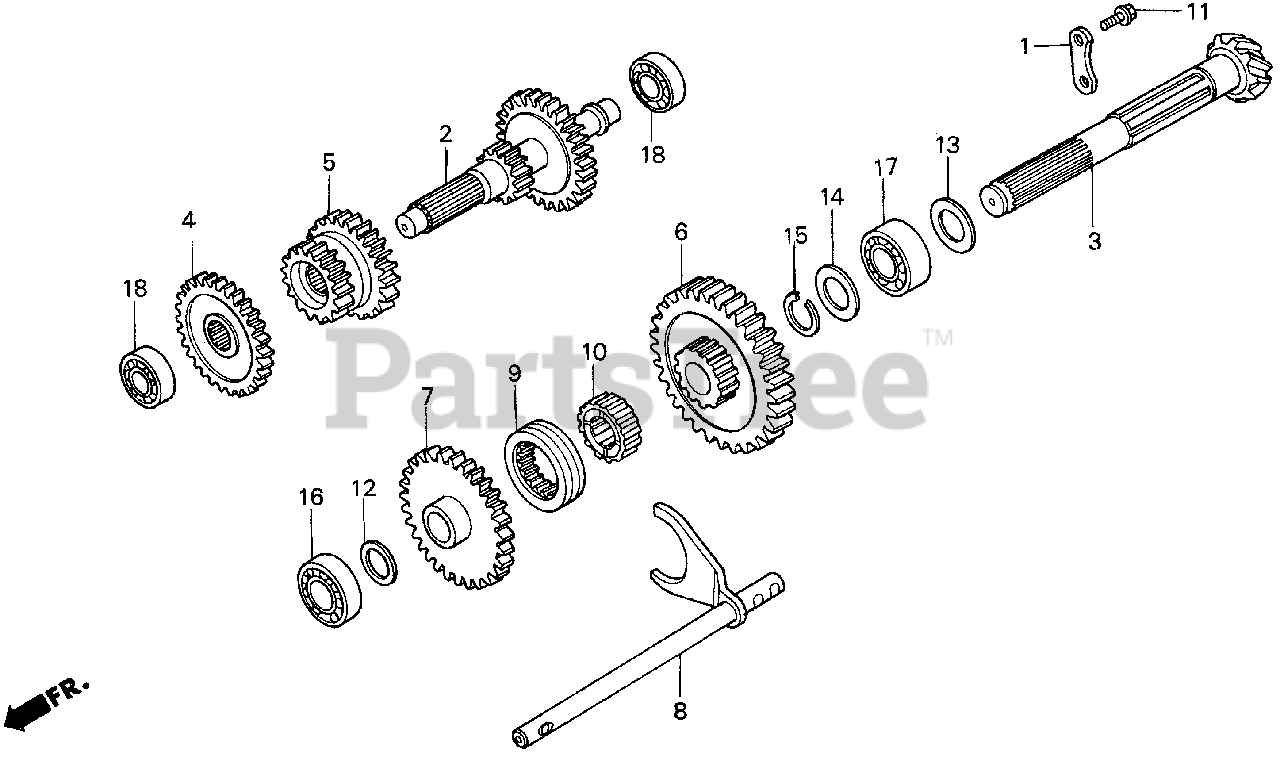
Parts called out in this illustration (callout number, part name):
1	PLATE B, BEARING STOPPER
2	COUNTERSHAFT (LOWER)
3	SHAFT, FINAL
4	GEAR, COUNTERSHAFT THIRD (39T)
5	GEAR, COUNTERSHAFT FOURTH (29T/17T)
6	SELECTOR KIT, AUXILIARY
6	GEAR, AUXILIARY LOW DRIVEN (39T)
6	GEAR, AUXILIARY DRIVEN HIGH (35T)
6	SELECTOR, AUXILIARY
7	SELECTOR KIT, AUXILIARY
7	GEAR, AUXILIARY DRIVEN HIGH (35T)
7	SELECTOR, AUXILIARY
8	FORK, AUXILIARY SHIFT
9	SELECTOR KIT, AUXILIARY
9	SELECTOR, AUXILIARY
10	HUB, AUXILIARY SELECTOR
11	BOLT, FLANGE (8X20)
12	WASHER, THRUST (22X32X1.0) (A)
12	WASHER, THRUST (22X32X1.1) (B)
12	WASHER, THRUST (22X32X1.2) (C)
12	WASHER, THRUST (22X32X1.3) (D)
12	WASHER, THRUST (22X32X1.4) (E)
12	WASHER, THRUST (22X32X1.5) (F)
12	WASHER, THRUST (22X32X1.6) (G)
12	WASHER, THRUST (22X32X1.7) (H)
12	WASHER, THRUST (22X32X1.8) (I)
12	WASHER, THRUST (22X32X1.9) (J) (NOT AVAILABLE)
12	WASHER, THRUST (22X32X2.0) (K)
13	SHIM (25X38X1.25) (A)
13	SHIM (25X38X1.3) (B)
13	SHIM (25X38X1.4) (D)
13	SHIM (25X38X1.45) (E)
13	SHIM (25X38X1.5) (F)
13	SHIM (25X38X1.55) (G)
13	SHIM (25X38X1.6) (H)
13	SHIM (25X38X1.65) (I)
13	SHIM (25X38X1.7) (J)
13	SHIM (25X38X1.75) (K)
14	SHIM, THRUST (25X38X1.3) (B)
14	SHIM, THRUST (25X38X1.35) (C)
14	SHIM, THRUST (25X38X1.4) (D)
14	SHIM, THRUST (25X38X1.45) (E)
14	SHIM, THRUST (25X38X1.5) (F)
14	SHIM, THRUST (25X38X1.55) (G)
14	SHIM, THRUST (25X38X1.6) (H)
14	SHIM, THRUST (25X38X1.65) (I)
14	SHIM, THRUST (25X38X1.7) (J)
14	SHIM, THRUST (25X38X1.75) (K)
15	CIRCLIP (OUTER) (25MM)
16	BEARING, RADIAL BALL (62/22)
17	BEARING, RADIAL BALL (25X52X20.6)
18	BEARING, RADIAL BALL (6203)
